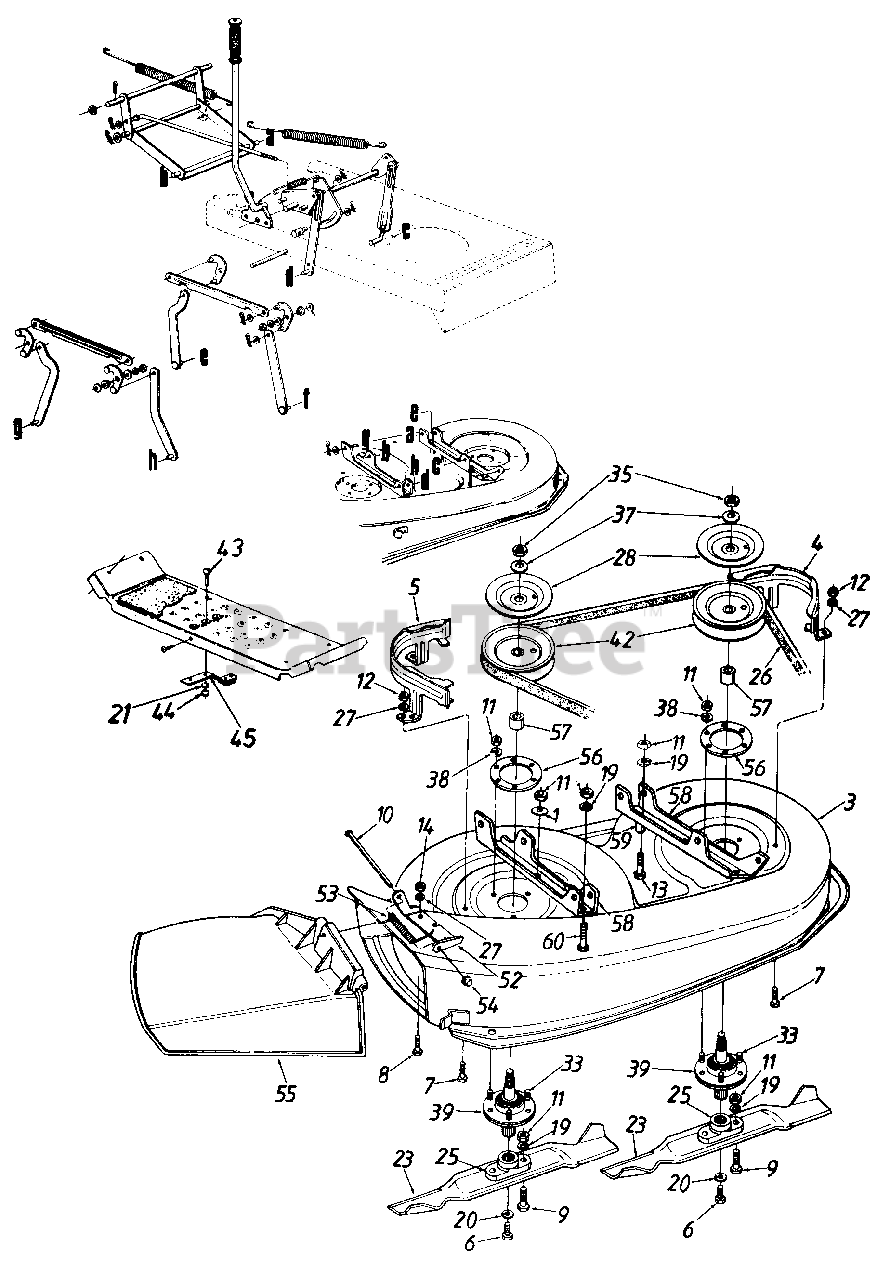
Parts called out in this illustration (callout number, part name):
1	Bell-Wash..345" I.D.
3	36" Deep Deck Ass'y.
7	Hex Bolt 1/4-28 x .62"
8	Truss Mach. Scr. 1/4-20 x .75"
9	Hex Bolt Special 5/16-24 x 1.0"
10	Hinge Pin
11	Hex Nut 5/16-24 Thd.
12	Hex Nut 1/4-28 Thd.
13	Hex Bolt 5/16-24 x 1.25" Lg.
14	Hex Jam Nut 1/4-20 Thd.
19	L-Wash. 5/16" I.D. *
20	L-Wash. 3/8" I.D.-H.D.
21	L-Wash. 1/4" I.D.
23	High-Lift Blade
25	Blade Adapter
26	V-Belt
27	Bell-Wash. 1/4" I.D.
28	Brake Disc
33	Rib Neck Bolt 5/16-24 x .84" Lg.
35	Hex Jam Nut 5/8-18 Thd.
37	L-Wash. 5/8" I.D.
38	L-Wash. 5/16" I.D.
39	Blade Spindle Ass'y. Comp.
42	5" Dia. Pulley
43	Carr. Bolt 1/4-20 x .62
44	Hex Nut 1/4-20 Thd.
45	Blade Brake Ass'y
52	Hinge Mtg. Brkt.
53	Torsion Spring
54	Push Nut
55	Chute Ass'y. Comp. (Plastic)
56	Reinforcement Plate
57	Spacer
60	Hex Bolt 5/16-24 x .75" Lg.
